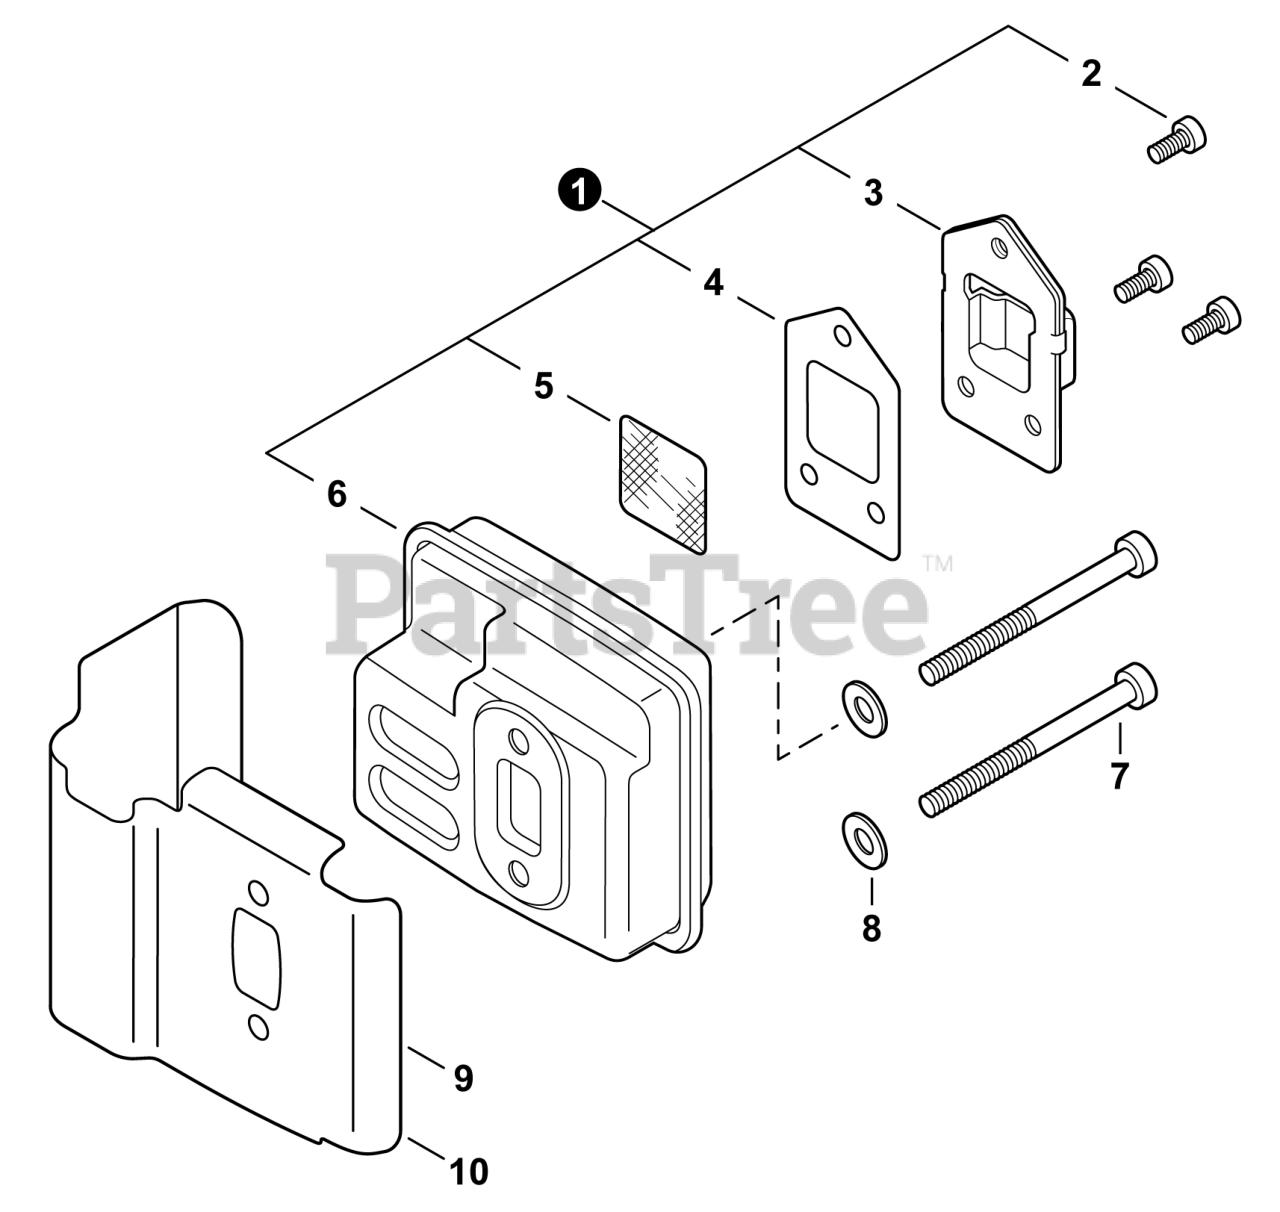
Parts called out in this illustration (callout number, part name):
1	MUFFLER ASSY
2	BOLT, TORX 4x8
3	GUIDE, EXHAUST
4	GASKET, EXHAUST
5	SCREEN, SPARK ARRESTER
7	BOLT 5x55
8	WASHER, FLAT 5.5x10x0.8
9	HEAT SHIELD, EXHAUST
10	GASKET KIT
